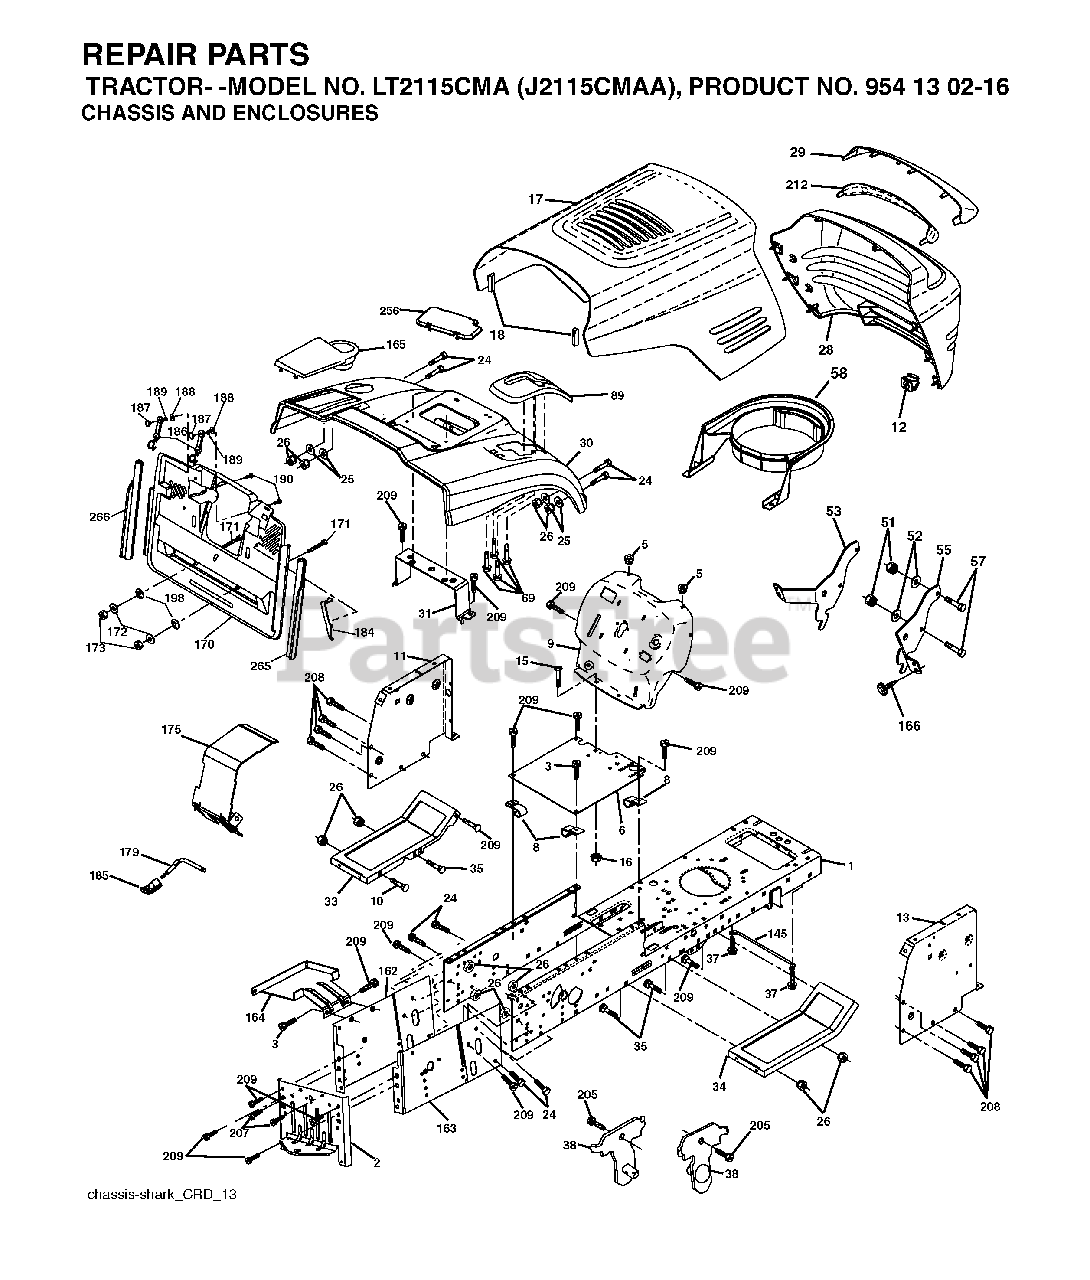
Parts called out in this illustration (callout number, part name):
1	CHASSIS
3	SCREW 3/8-16X3/4
5	BUMPER.RUBBER.HOOD
8	CLIP,INSULATOR
10	BOLT D
11	PANEL.DASH.LH.LTX
13	PANEL ASM, DASH RH
16	NUT
18	BUMPER.HOOD.LARGE.1.75"
25	WASHER
26	NUT
31	BRACKET SUPPORT FENDER
51	LOCKNUT
54	SCREW
57	BOLT
69	SCREW.HI-LO.CONSOLE
145	ROD PIVOT CHASSIS/HOOD
164	SUPPORT
171	BOLT
172	WASHER
186	LATCH ASSY
187	WELDNUT
189	LOCKWASHER
207	SCREW, 5/16-18 X 1/2
208	SCREW 3/8-16X1/2
209	SCREW, 3/8-16X3/4
